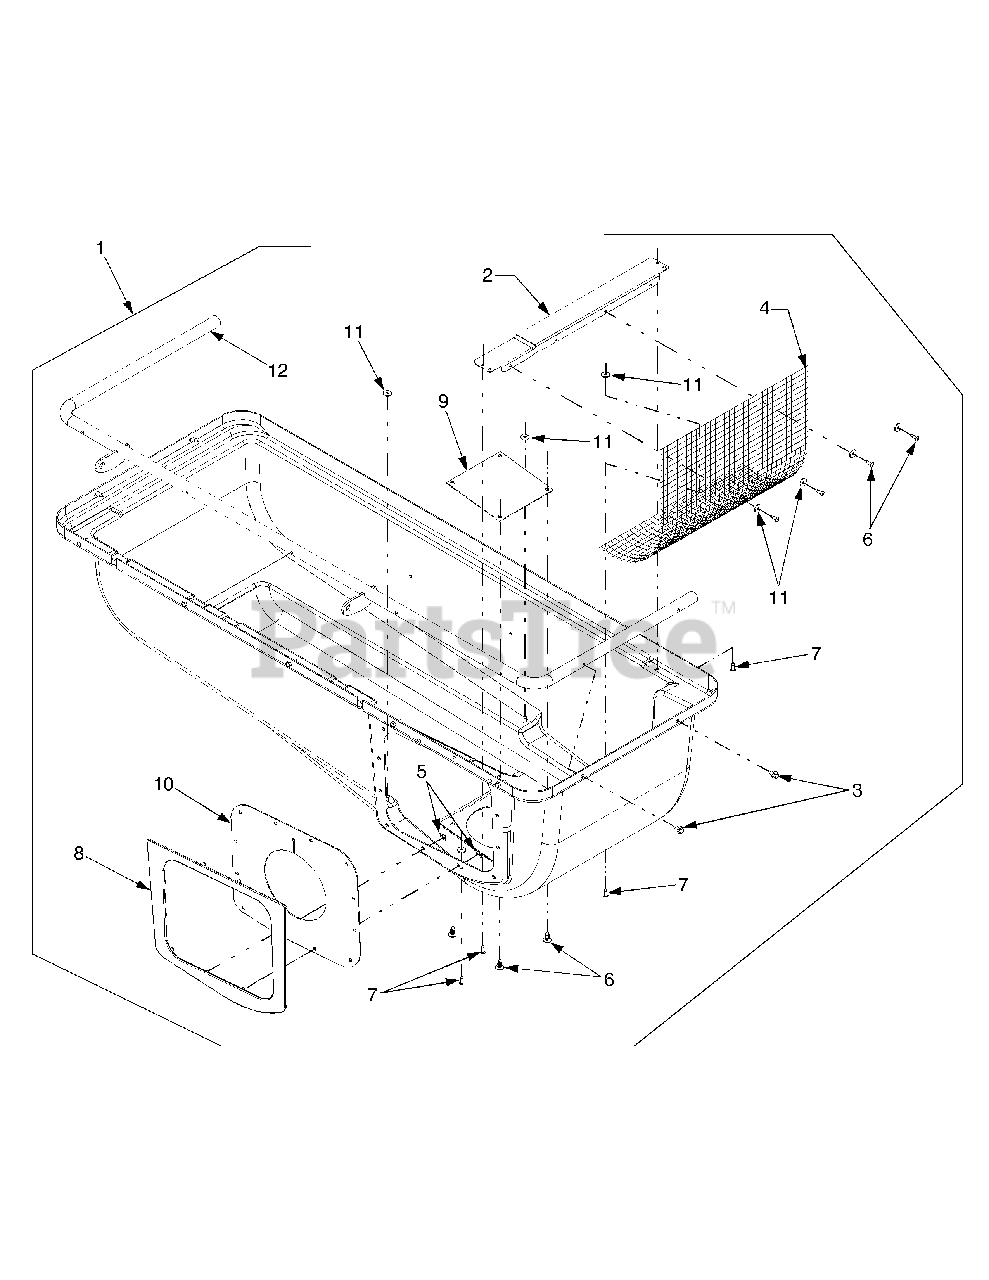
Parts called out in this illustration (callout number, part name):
1	Cover Assembly
1	Label, Warning
1	Decal, Cub Cadet
1	Speed Nut, Push On
4	Screen
5	Speed Nut, Push On
6	Clip, Ratchet
7	Rivet, Pop, .187 x .45
8	Retainer, Seal
9	Plate, Plastic
10	Seal, Tube
11	Washer, Flat, .194 x .62 x .063
12	Bracket Assembly, Cover Hinge
